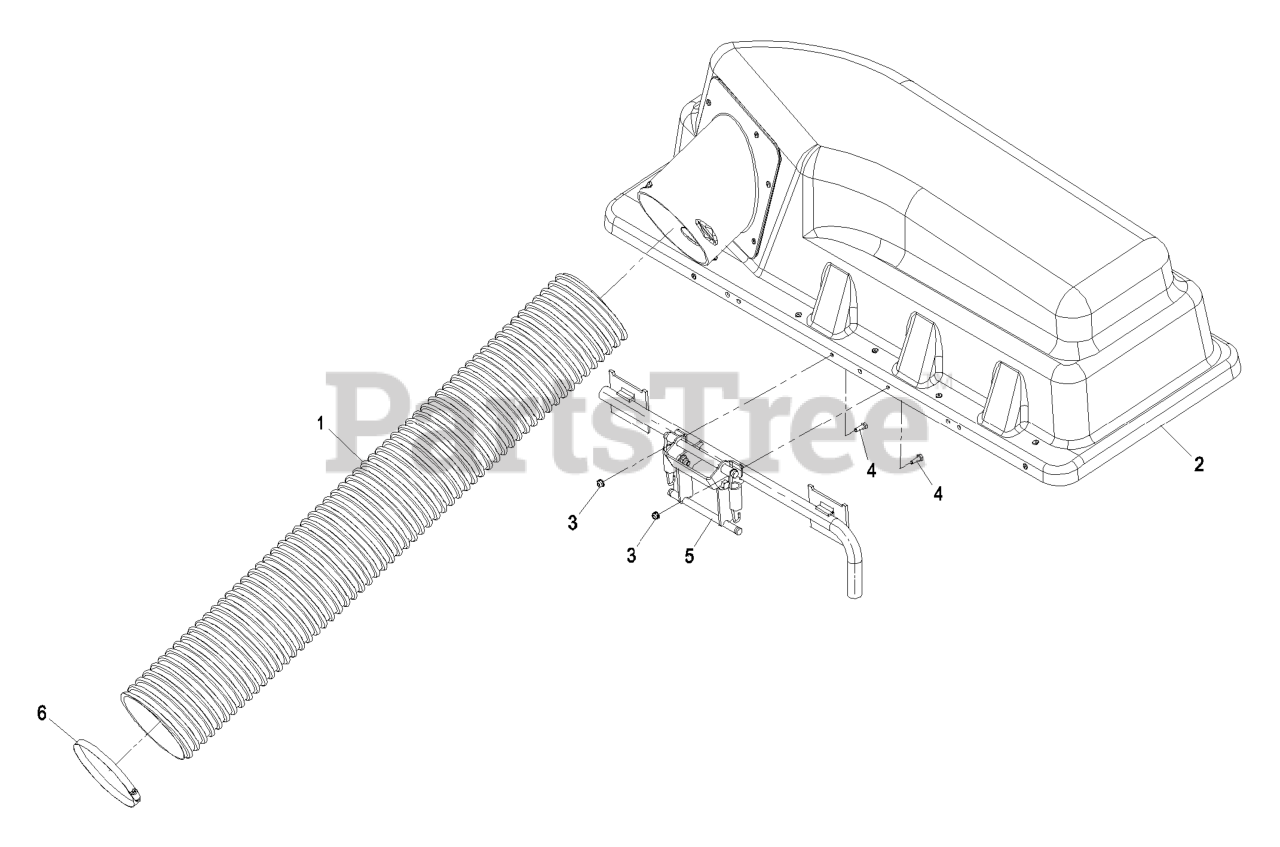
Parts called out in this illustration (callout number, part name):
1	HOSE,FLEXIBLE
2	ASM,BAGGER HOOD
4	SCREW-HH
5	ASM,BAGGER MOUNT
